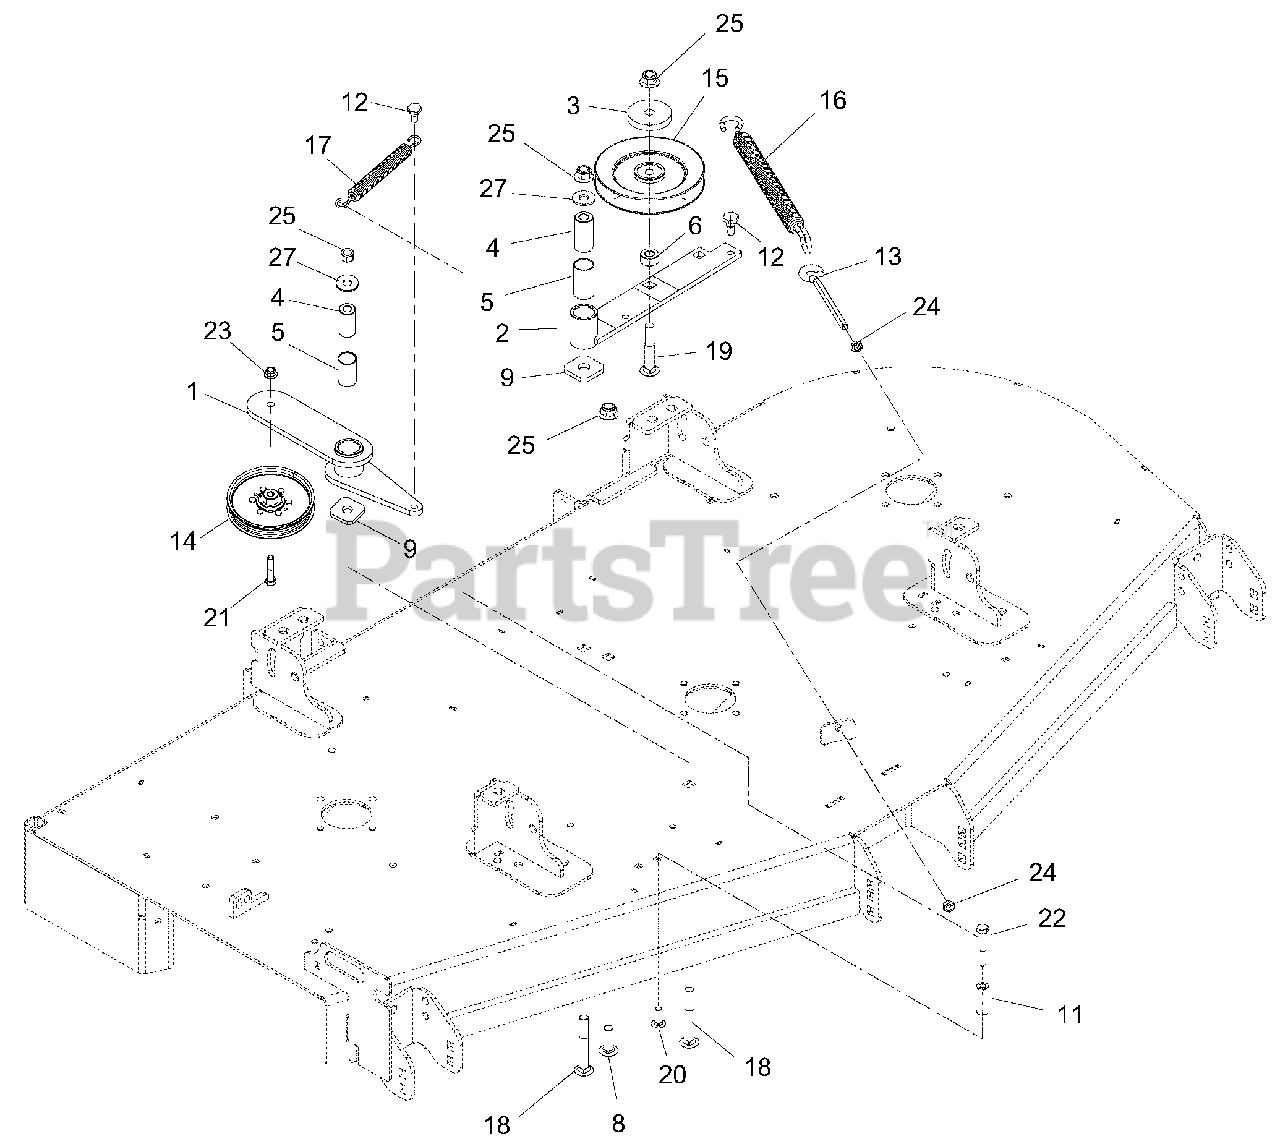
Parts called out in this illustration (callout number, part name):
1	WMT, IDLER ARM
2	WMT, IDLER PIVOT ARM
3	CAP, IDLER BEARING SEALING
4	BSHG, SPCR .502X.997X2.03
5	BSHG, 1.00X1.125X1.937
6	BSHG, SPCR .502 X .997.50 PM
8	BLT, RNHDSQSHNK 1/2-13 X 2.00 FULL
9	WSHR, -FLT.640X1.75X.250
11	NUT-HEX COUPLING
12	BLT, SHLDR EP .38-16X.30 HEX
13	BOLT, .38-16X6.00 .62 DIA EYE
14	SHV, .38" ID X 5.0’’ OD V-IDLER
15	SHEAVE, .50" ID X 6.00" OD V-IDLER
16	SPRG, EXTENSION
17	SPRG, EXT. .845 X 6.55
18	BLT-RDHDSQNK .50-13X3.50YG5
19	BLT-RDHDSQNK .50-13X3.00YG5
20	BLT-RDHDSHSQNK.38-16X1.0 G5YZ
21	BLT-HEX .38-16X2.00 GR5 YWZC
22	BLT-HEX .38-16X1.75 GR5 YWZC
23	NUT-LK-NYL-FLG .38-16 YWZC
24	NUT, 3/8-16 JAM GR5
25	NUT-LK-NYL-FLG .50-13 YWZC
27	WSHR-FL-STL.563X1.38X.109YWZC
